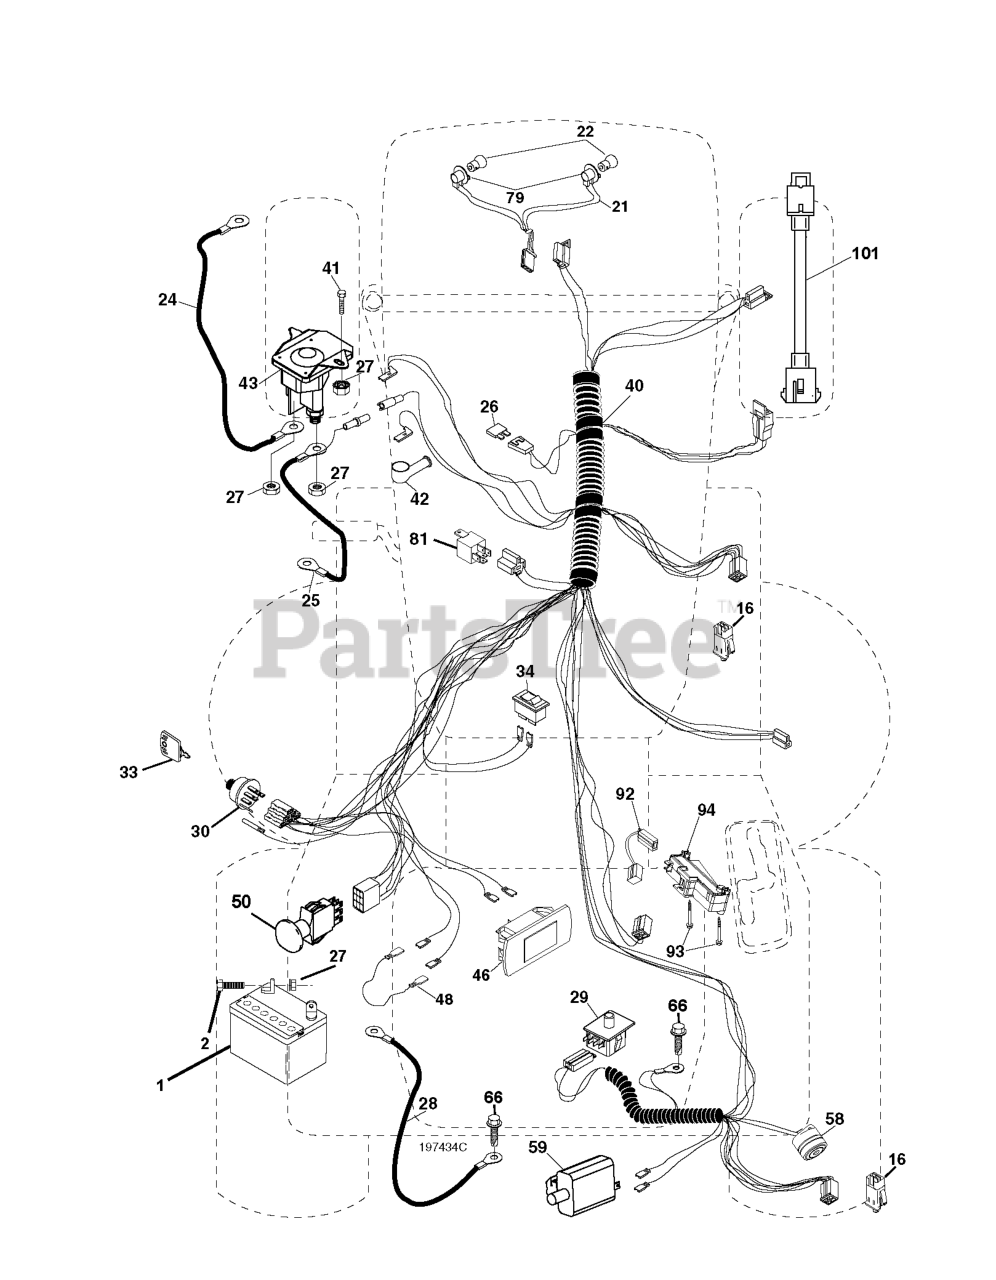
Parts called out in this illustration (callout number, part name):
1	BATTERY 12V .35 AMP
2	BOLT.HEX.1/4.X.3/4.DICHROMATE
16	SWITCH INTERLOOK PUSH-IN
21	HARNESS.LIGHT W/4152J BULBS
24	BATTERY CABLE GT
25	CABLE BATTERY
26	FUSE 20AMP
27	NUT
28	CABLE GROUND
29	SWITCH.SEAT.DP W/RAMPS
30	SWITCH.IGN.DELTA.W.LGH.ROS
33	KEY MLD GEN DELTA
40	RP HARNESS.IGN.ELECT.REG.CRD
41	BOLT
42	TERMINAL COVER
43	SOLENOID.W/BRASS.PLUNGER
46	RP.GUAGE.SRVCMNDR.HRMTR.
48	ADAPTER.AMMETER
50	RP.PTO.SWITCH.8 TERMINAL.BLACK
58	BUZZER
59	.WITCH.FULL BAGGER.INDICATOR
79	BULB HOLDER ASM.
81	RELAY.ASSY.T
92	HARNESS.PIGTAIL.CONSLE
93	SCREW.PLASTITE
94	MODULE.REVERSE.ROS
101	PIGTAIL.MATNLK.NEW.HAR
